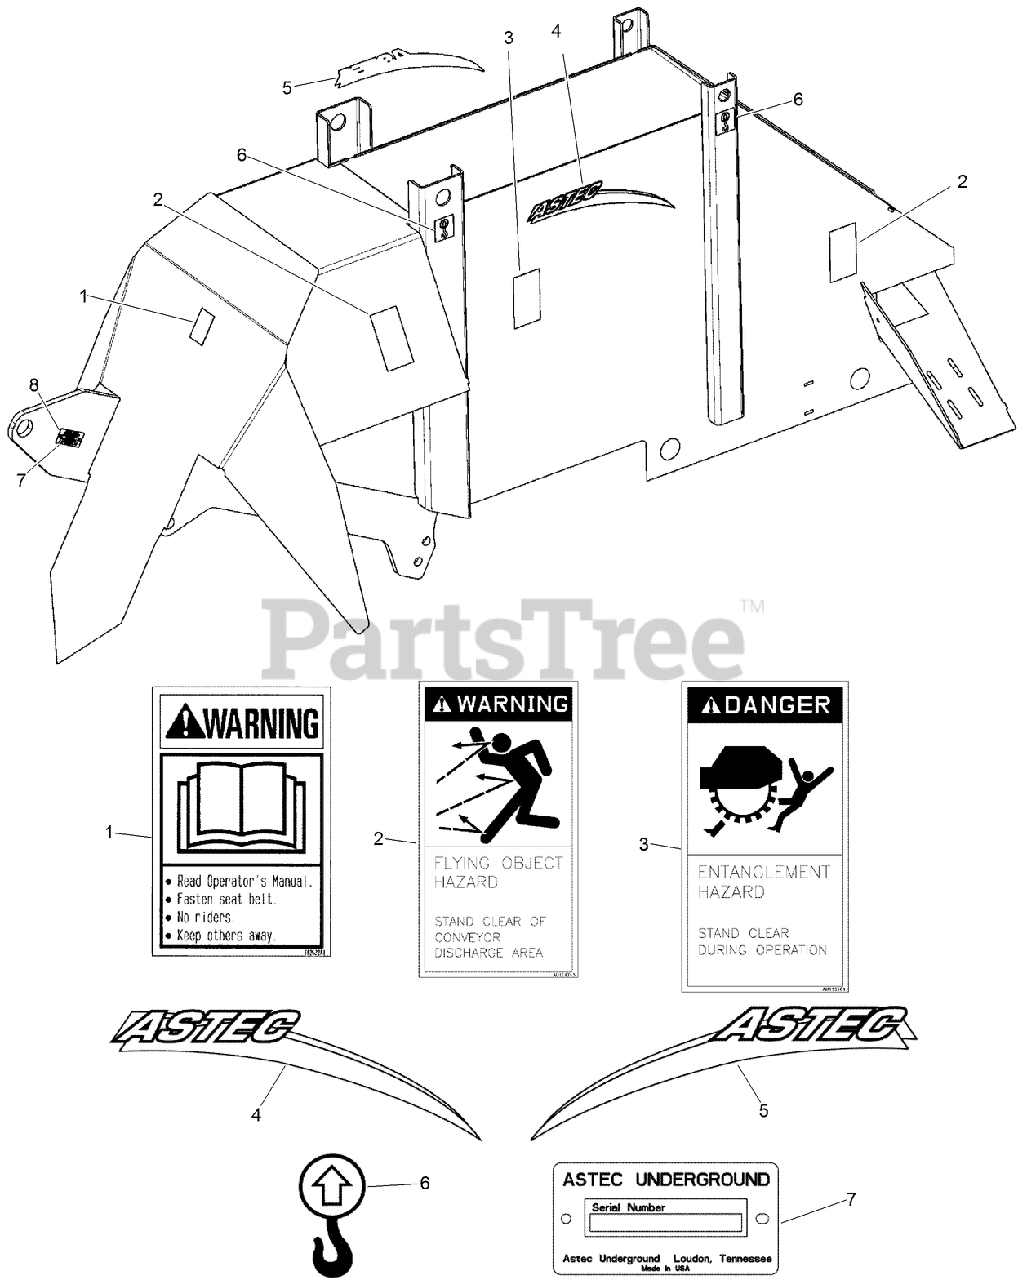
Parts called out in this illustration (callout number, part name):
1	DECAL - Warning, General Operation
2	DECAL - Wheel Hazard
3	DECAL - Danger, Tren Entangle Hazard
4	DECAL-Astec
5	DECAL-Astec
6	DECAL - Lift Hook Location
7	PLATE - Serial Number
8	TACK-FASTENER, STEEL
